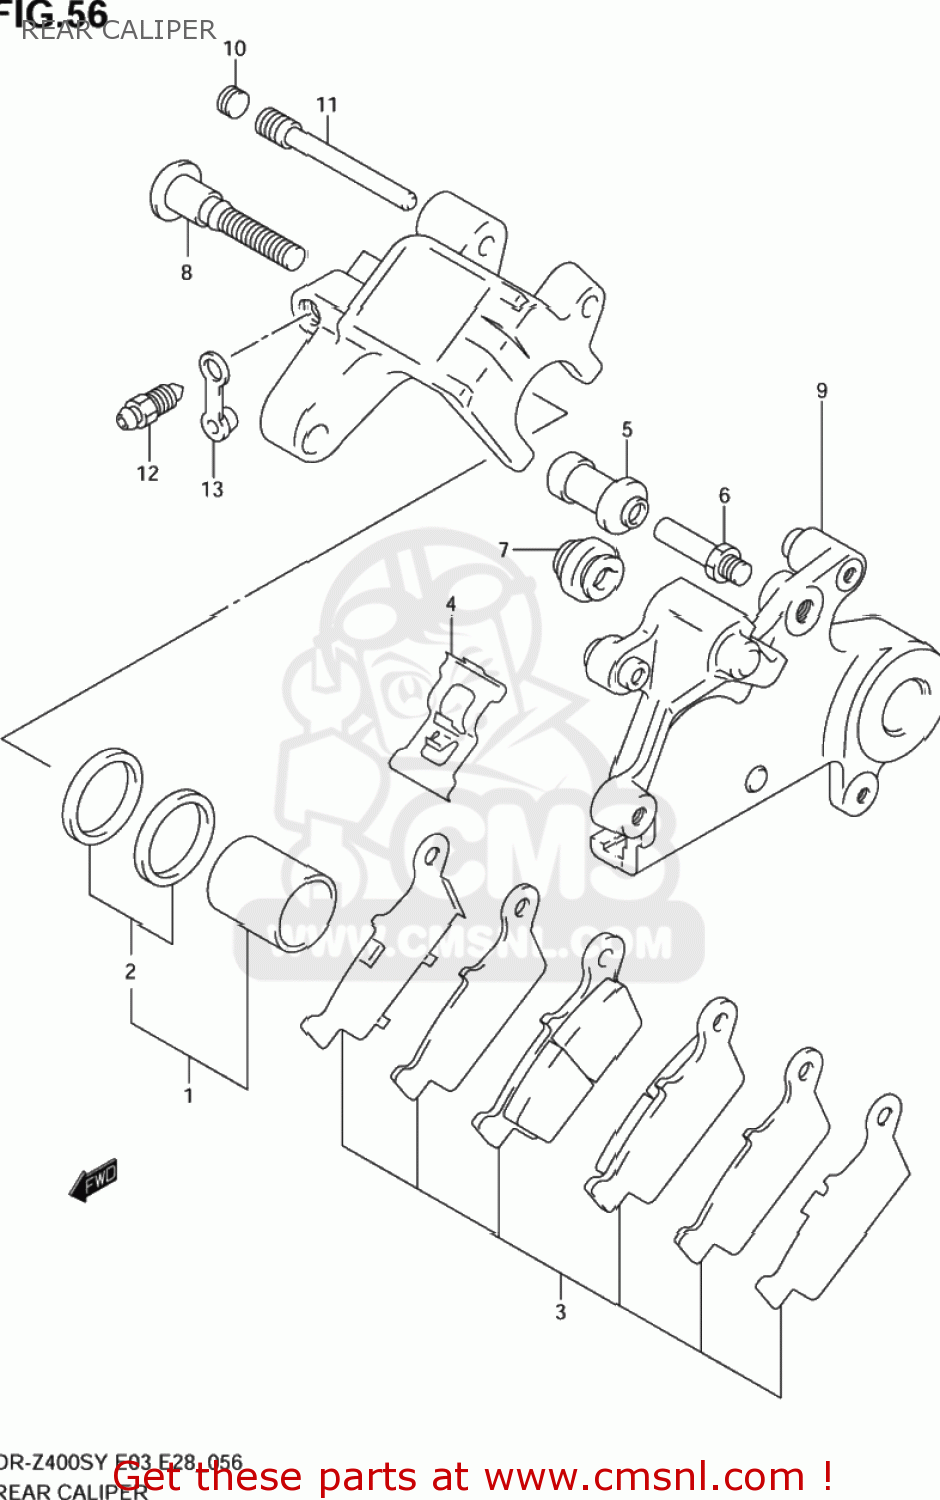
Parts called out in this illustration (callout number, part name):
1	PISTON SET
2	SEAL SET,PISTON
3	PAD & RETAINER SET
4	SPRING,PAD
5	BOOT
6	BOLT
7	BOOT
8	PIN,BOLT
9	BRACKET
10	PLUG,PIN
11	PIN,HANGER
12	BLEEDER
13	CAP,BLEEDER
